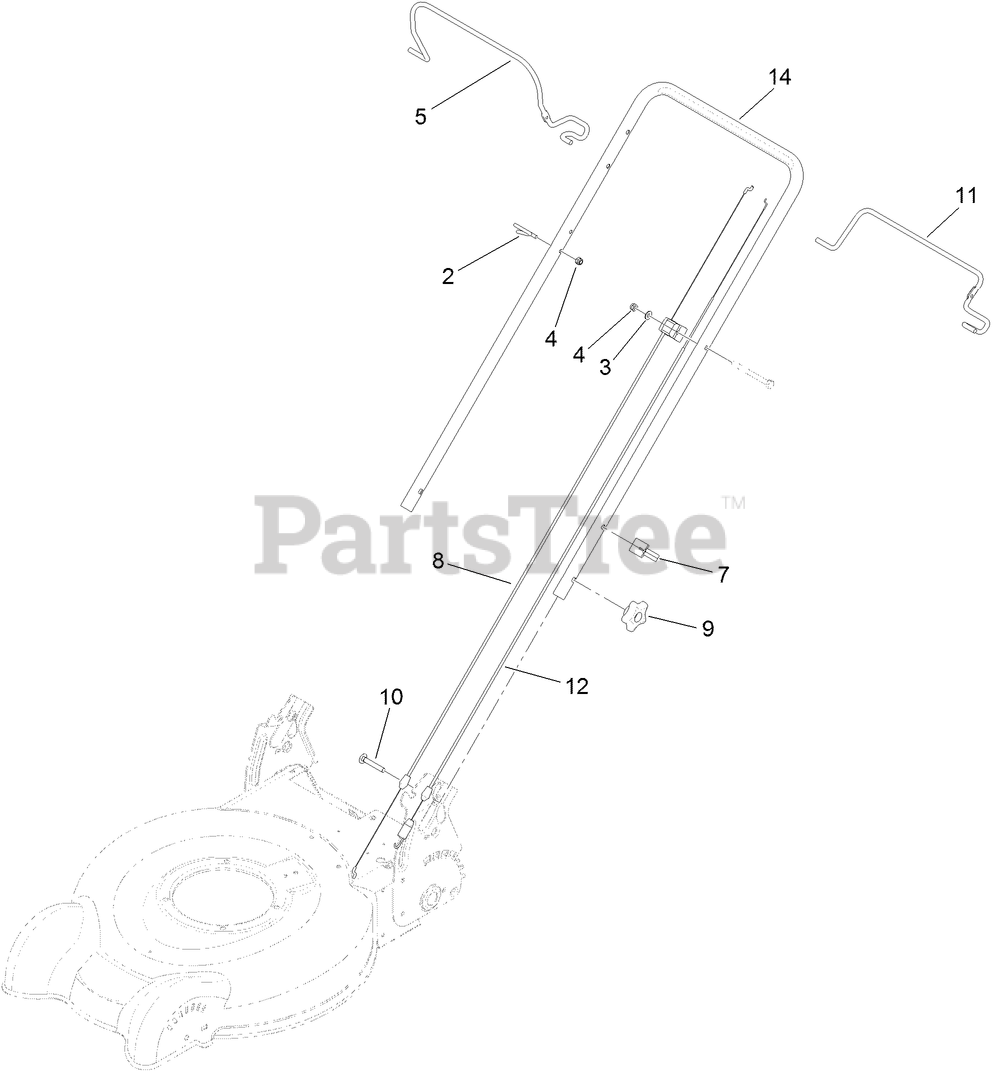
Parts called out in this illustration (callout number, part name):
2	GUIDE-ROPE
3	WASHER-FLAT
4	NUT-LOCK, NI
5	BAIL-BRAKE
7	GUIDE-CABLE
8	CABLE-BRAKE
9	KNOB-HANDLE
10	BOLT-CARR
11	BAIL-TRACTION, 2-BAIL FLAT
12	CABLE-TRACTION
14	HANDLE
